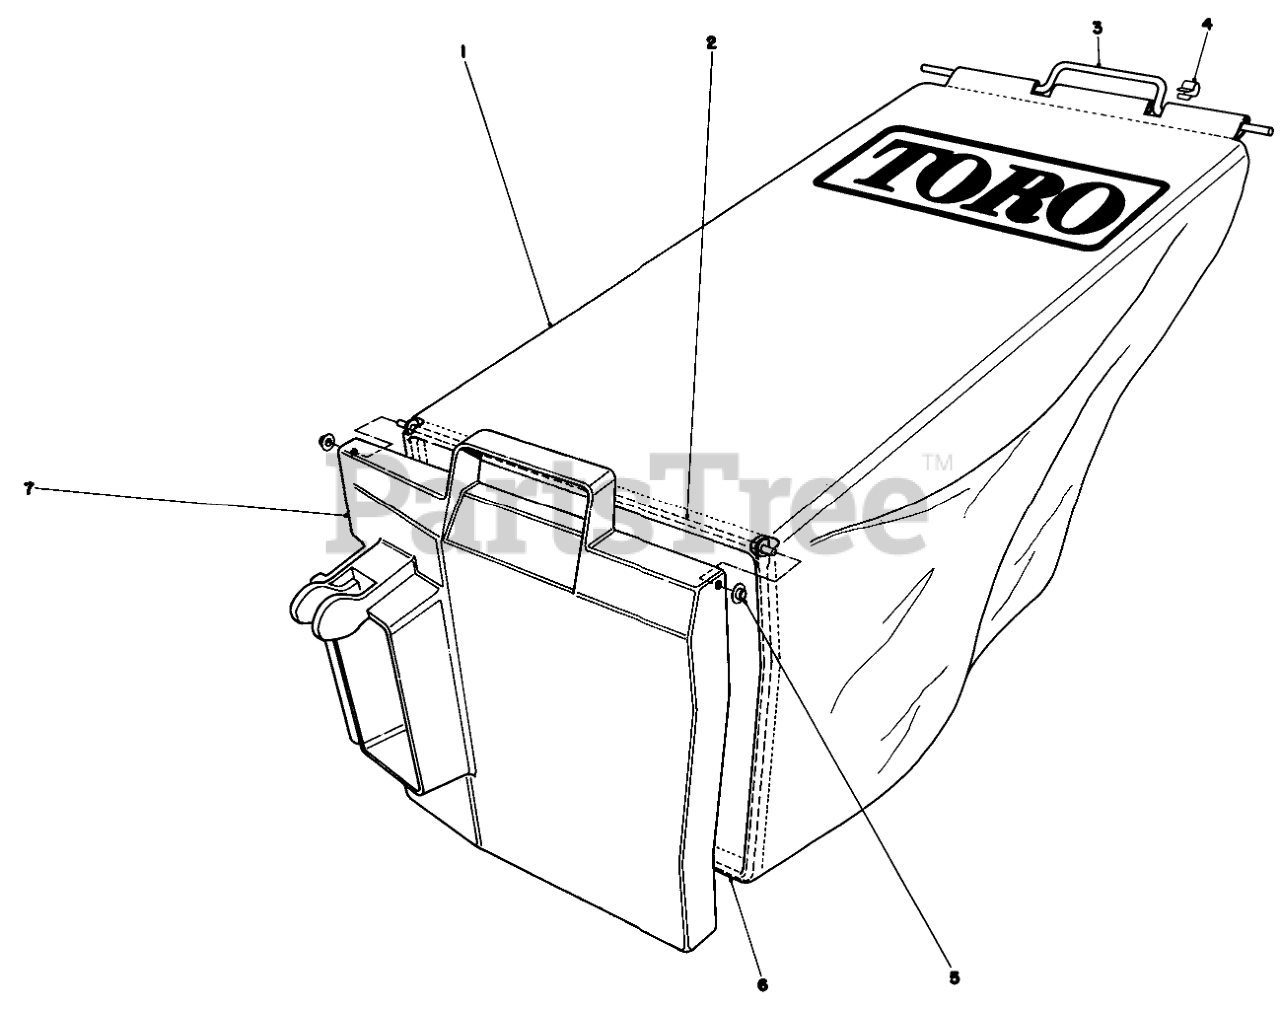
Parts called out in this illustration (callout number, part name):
1	18 BAGGER BAG 33-4552
2	HINGE
3	Handle Bag
5	NUT-PUSH
6	Frame Bag
7	Door-Bag
